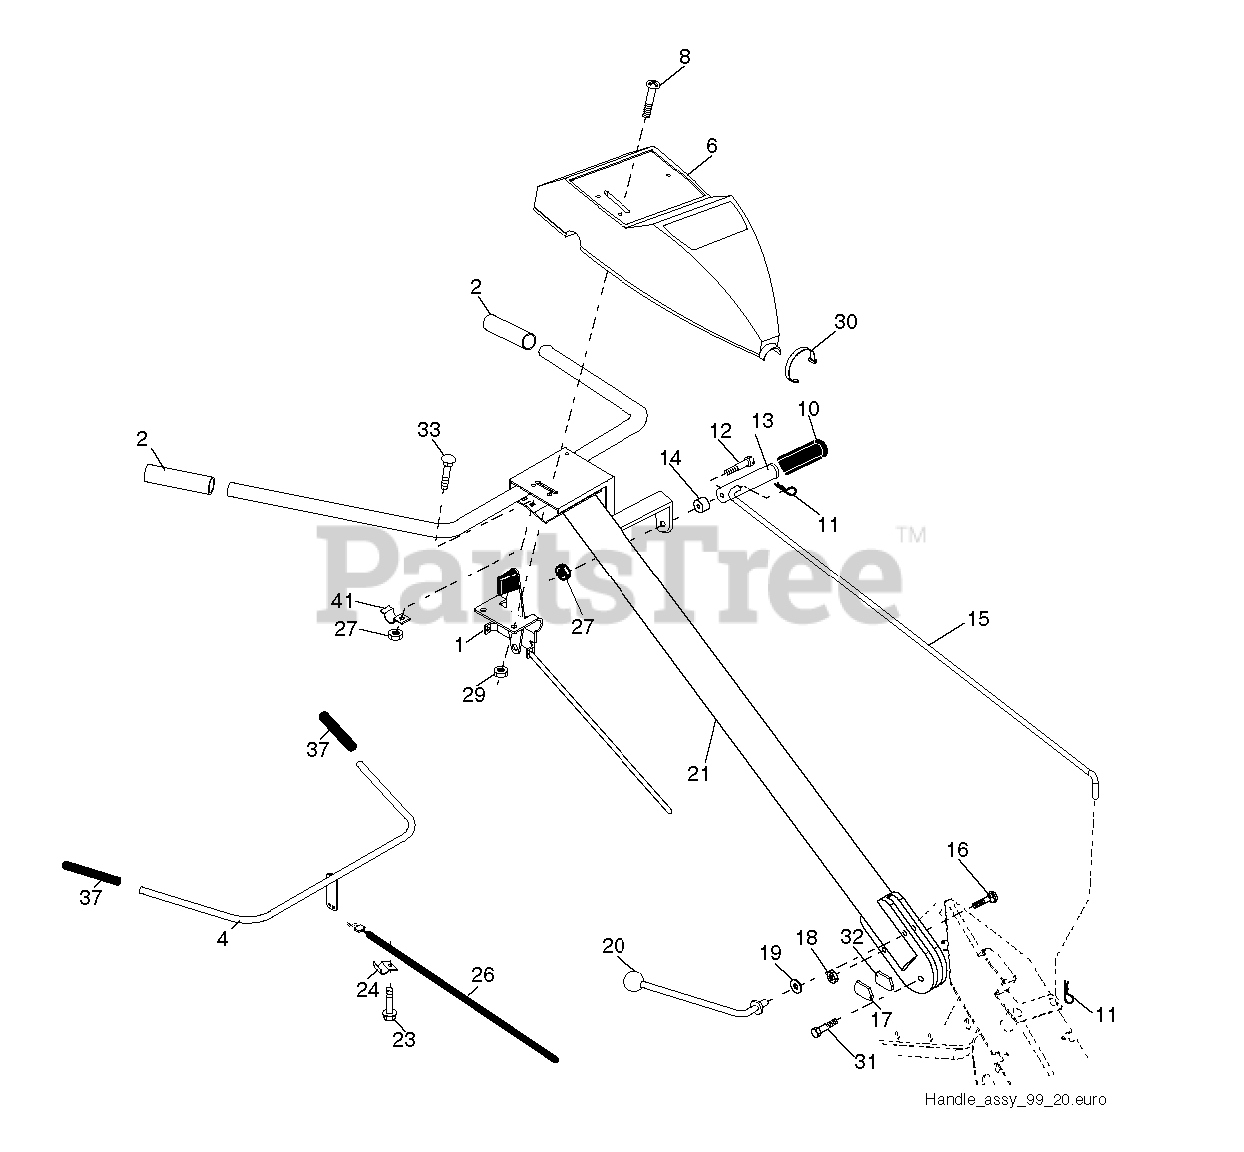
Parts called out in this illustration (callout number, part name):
1	THROTTLE.CONTROL.
2	GRIP.1X5.06
4	CONTROL BAR ASSY
6	RP CONTROL PANEL
8	SCREW.PNHD.10-24
10	GRIP T
11	RETAINER M
12	SHOULDER BOLT ST
13	HANDLE.SHIFT.TILLER
14	GROMMET.RUBBER.CRT.TILLER
15	ROD.SHIFT.YARD PRO.UNIVERSAL.
16	BOLT D
17	LOCK.HANDLE.CRT
19	WASHER CRT
20	LEVER.LOCK.CRT
21	REPL BY 532 1805-17
23	TAPPING SCREW
24	CONDUIT.CLIP.PLATED
26	CABLE.CLUTCH
27	NUT T
29	NUT **
30	TIE CABLE CRT
31	BOLT.PIVOT
32	LOCK HANDLE
37	GRIP BAR CRT(1)
41	CLAMP.BAR.CRT.BLACK
